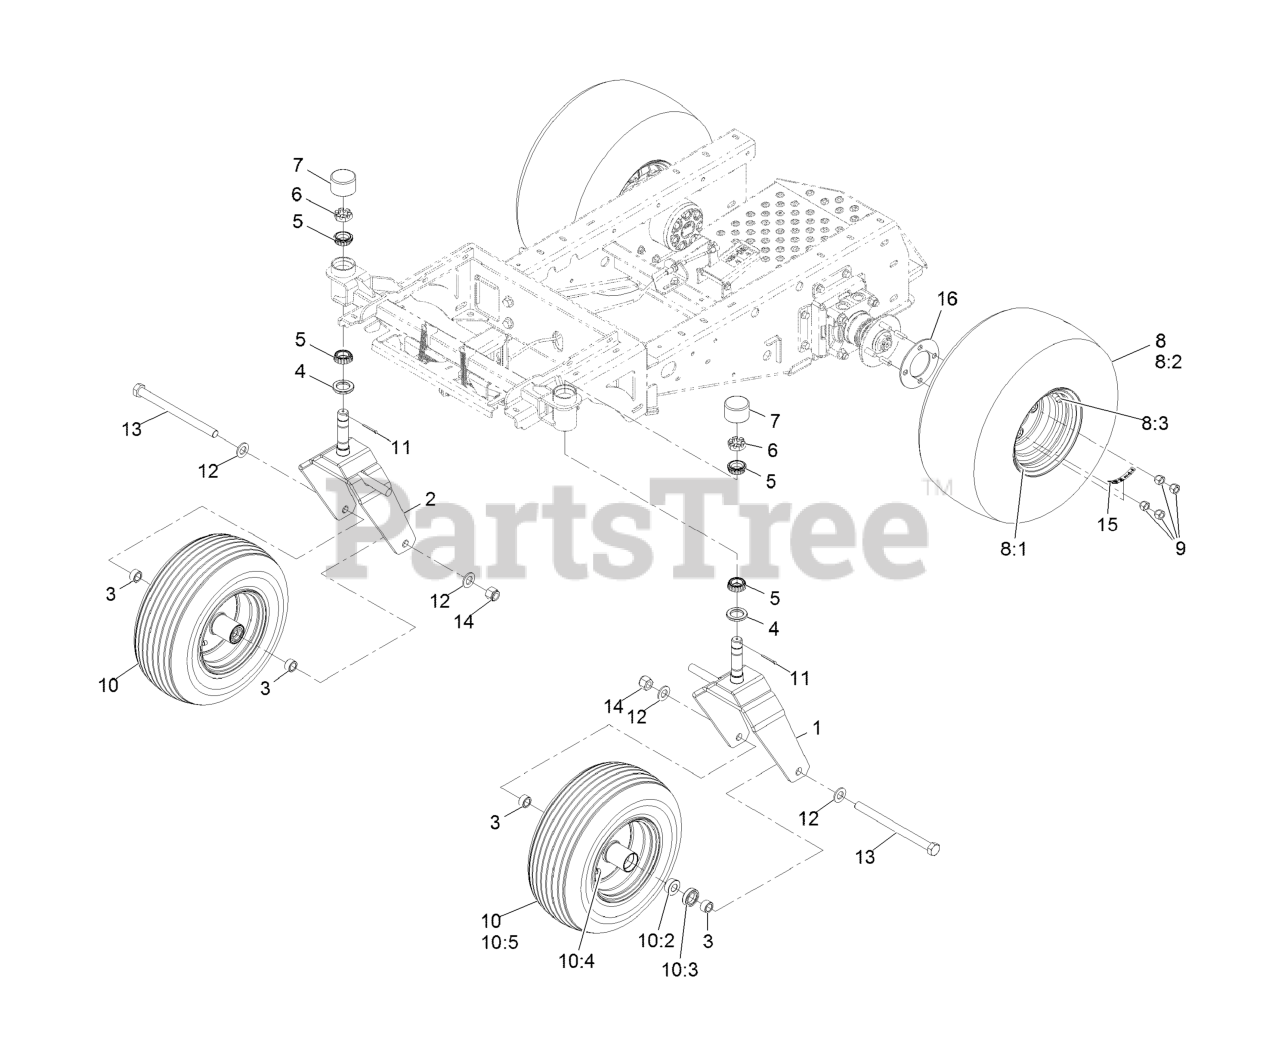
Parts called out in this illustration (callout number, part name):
1	X-REF TO 135-5441-03
2	X-REF TO 135-5446-03
3	SPACER-AXLE
4	SEAL-GREASE
5	CONE-BEARING, OUTER
6	NUT-SHH
7	CAP-DUST, RUBBER
8	WHEEL AND TIRE ASM
8:1	Rim-8 X 7, Black
8:3	Stem-Valve
9	NUT-LUG
10	WHEEL AND TIRE
10:2	BEARING-CONE, TAPERED ROLLER
10:3	SEAL-CASTER
10:4	VALVE
10:5	Tire-Rib
11	Pin-Cotter
12	WASHER-FLAT
13	SCREW-HH
14	NUT-LOCK, NI
15	DECAL-TORQUE, WHEEL HUB LUG
16	SPACER-WHEEL
